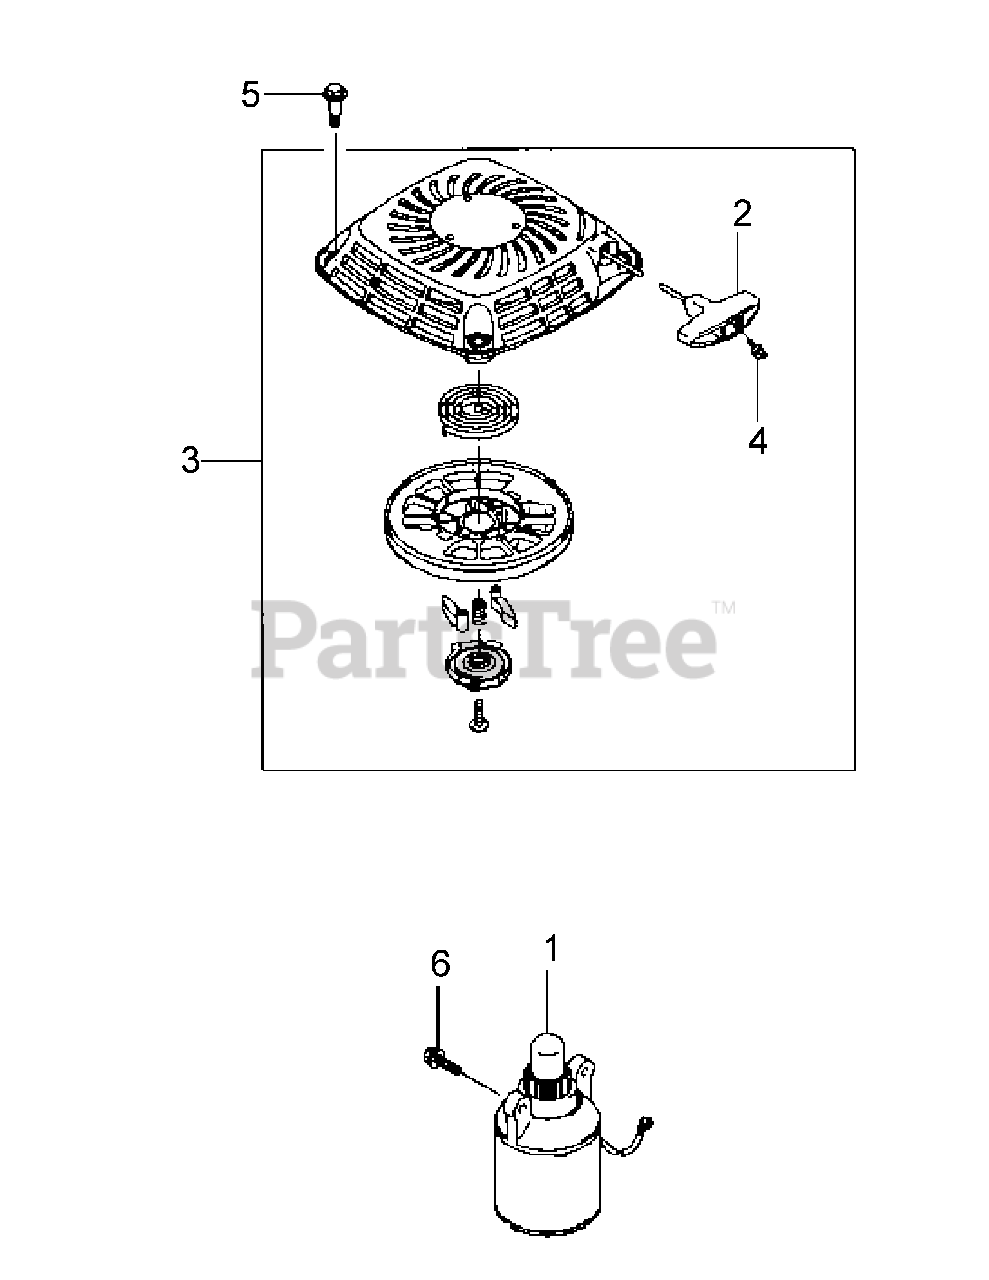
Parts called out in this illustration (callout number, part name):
1	Electric Starter
3	Recoil Starter
5	Bolt, M6
6	Flanged Bolt
